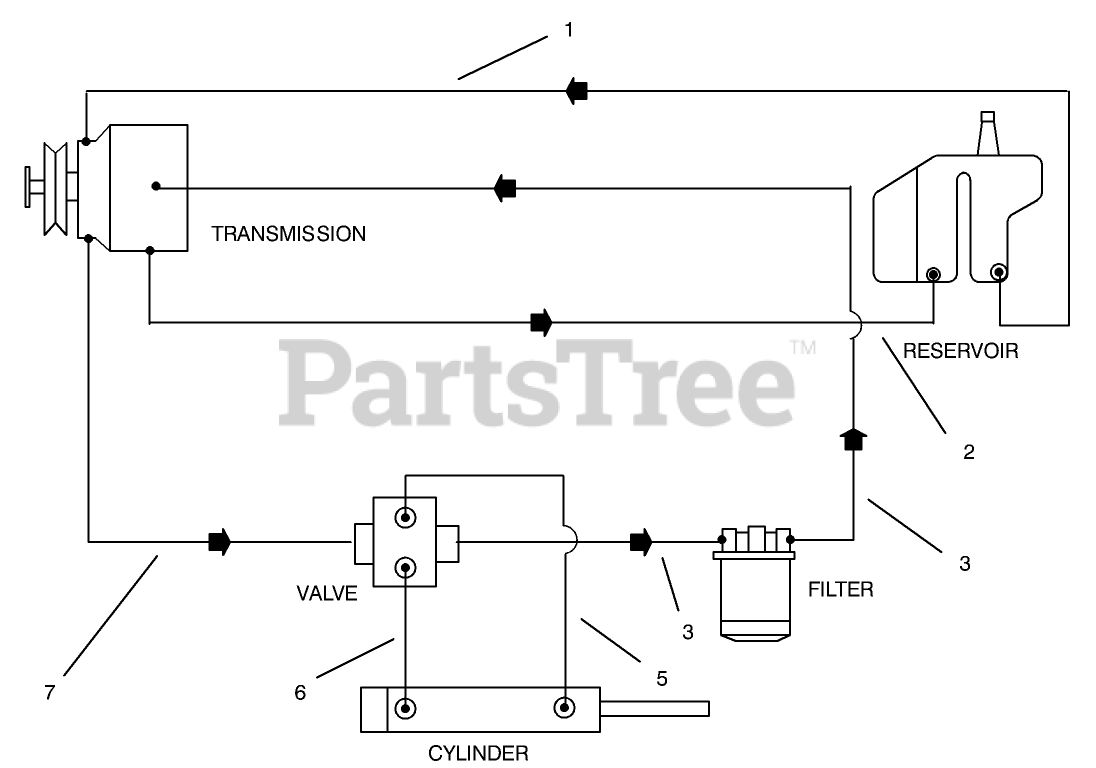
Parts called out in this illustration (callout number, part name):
1	HOSE-RESV TO PUMP
3	HOSE-ASM - HYD
5	HOSE ASM
6	HOSE ASM
7	HOSE ASM
